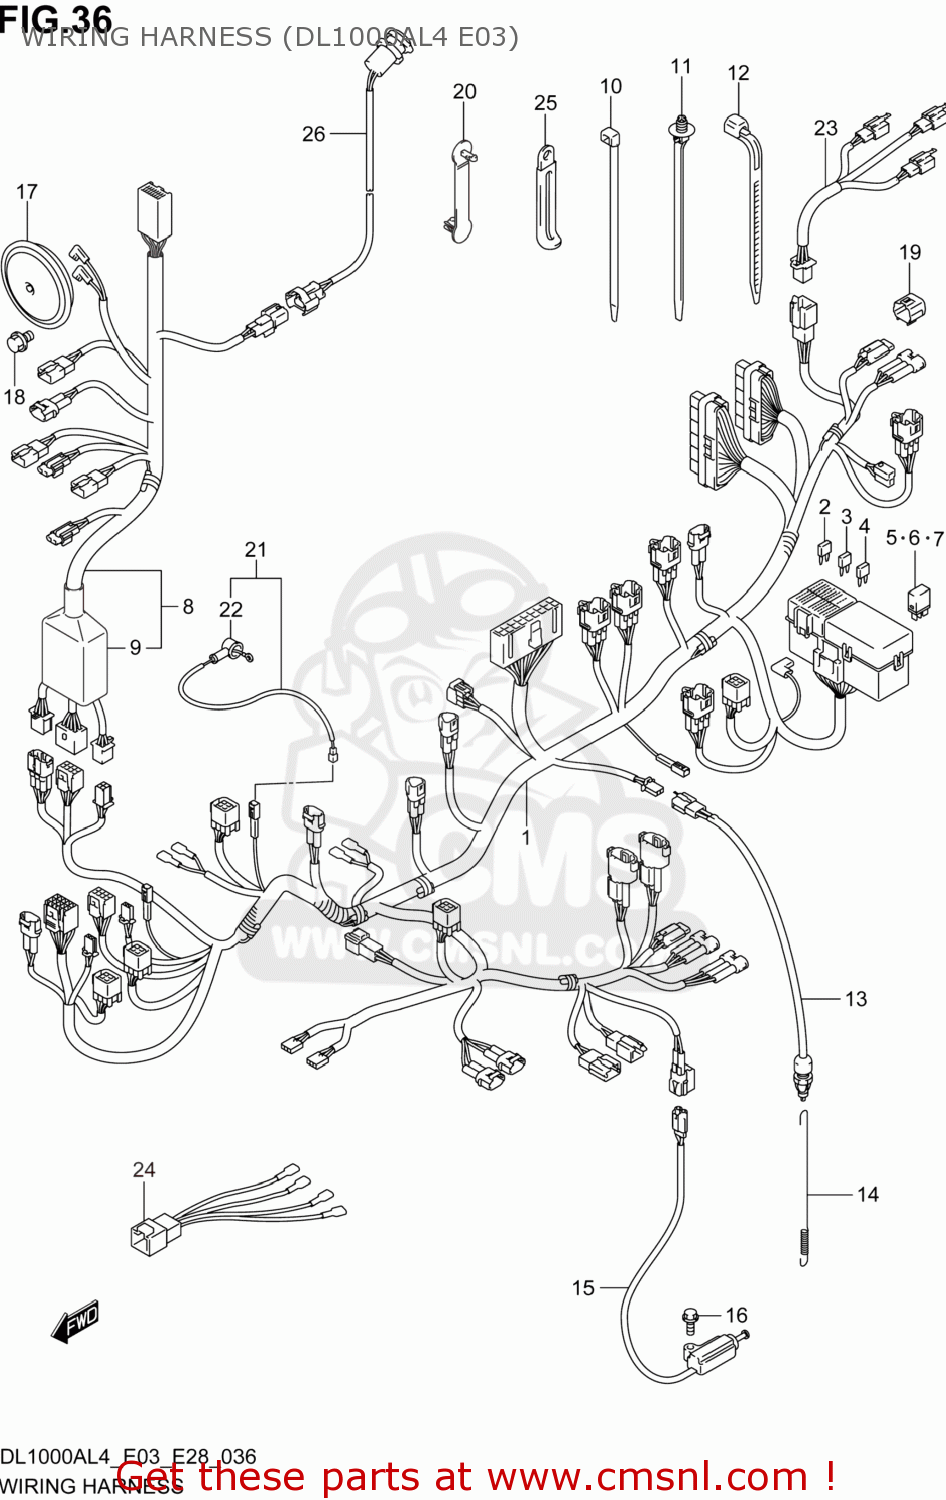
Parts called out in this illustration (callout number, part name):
1	HARNESS,WIRING NO.1
2	FUSE(10A)
3	FUSE(15A)
4	FUSE(25A)
5	RELAY ASSY
6	RELAY ASSY
7	RELAY ASSY
8	HARNESS,WIRING NO.2
9	COVER,CONNECTOR
10	CLAMP(L:145)
11	CLAMP(L:154)
12	CLAMP(L:125)
13	SWITCH ASSY,STOP LAMP
14	SPRING,STOP LAMP SWITCH
15	SWITCH ASSY,SIDE STAND
16	BOLT(8X35)
17	HORN ASSY
18	BOLT
19	CAP,TS
20	CLAMP(L:63)
21	WIRE,OIL PRESSURE SWITCH LEAD
22	CAP,OIL PRESSURE SWITCH
23	WIRE,REAR TURNSIGNAL LEAD
24	WIRE,REAR COMB LEAD
25	CLAMP(L:45)
26	TERMINAL,POWER SOURCE
